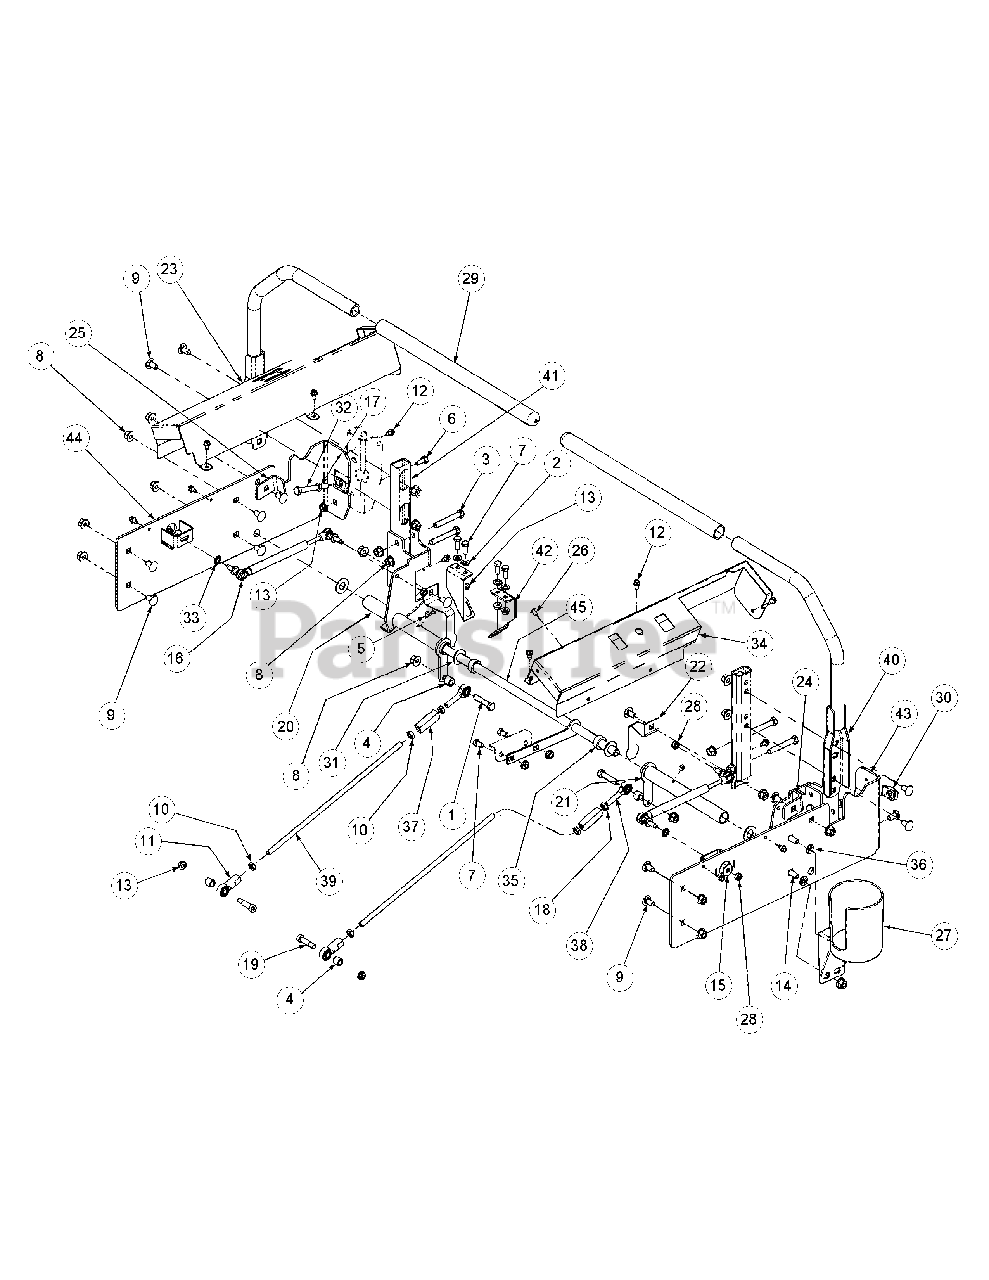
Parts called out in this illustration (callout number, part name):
1	Capscrew, 3/8-16 x 1-3/4
2	Flat Washer, 5/16
3	HHCS, 3/8-16, 2.25
4	Spacer, .625 OD x .385 ID x 1/2
5	Grease Fitting, 90 degree
6	HHCS, 5/16-18 x 1.0
7	Hex, Cap Screw, 5/16-18 x 3/4
8	Hex Nut, 3/8-16, Lock Flange
9	Carriage Bolt, 3/8-16 x .75
10	Hex Jam Nut, 3/8-24
11	B/Joint, 3/8-24, Right Hand Female
12	Screw, TT, 1/4-20, 0.5, Hex Index Washer
13	Nut, Lock, HexFlange, 5/16-18
14	Carriage Bolt, 3/8-16 x 1
15	Belle Washer, .325 x .930 x .045
16	Cylinder Return to Neutral
17	Nut, 3/8-16, Jam
18	Nut, 3/8-24, Jam, LH Third
19	Screw, Shoulder Control Rod
20	Hub Assy, Control LH Bearing
21	Hub Assy, Control RH Bearing
22	Lever, Safety Switch
23	Control Panel, LH
26	Screw Button Head, 1/4-20 x .5
27	Cup Holder Assembly
28	Nut, Hex, Center Lock, M8
29	Grip, 1.0
30	U-Nut, 3/8-16, .75
31	Flat Washer, 5/8 Nylon
32	HHCS, 3/8-16, 3.00
33	External Washer, 3/8
34	Control Panel, RH
35	Shaft Collar
36	Push Retainer
37	Turnbuckle
38	B/Joint, 3/8-24, Left Hand Female
39	Rod Connector 3/8 OD x 14.25
40	Lapbar, Handle Assembly
41	Mounting Handle
42	Switch Mounting Bracket, Lapbar
43	Side Panel, Control, Right
44	Side Panel, Control, Left
45	Shaft Control Brake Steering
